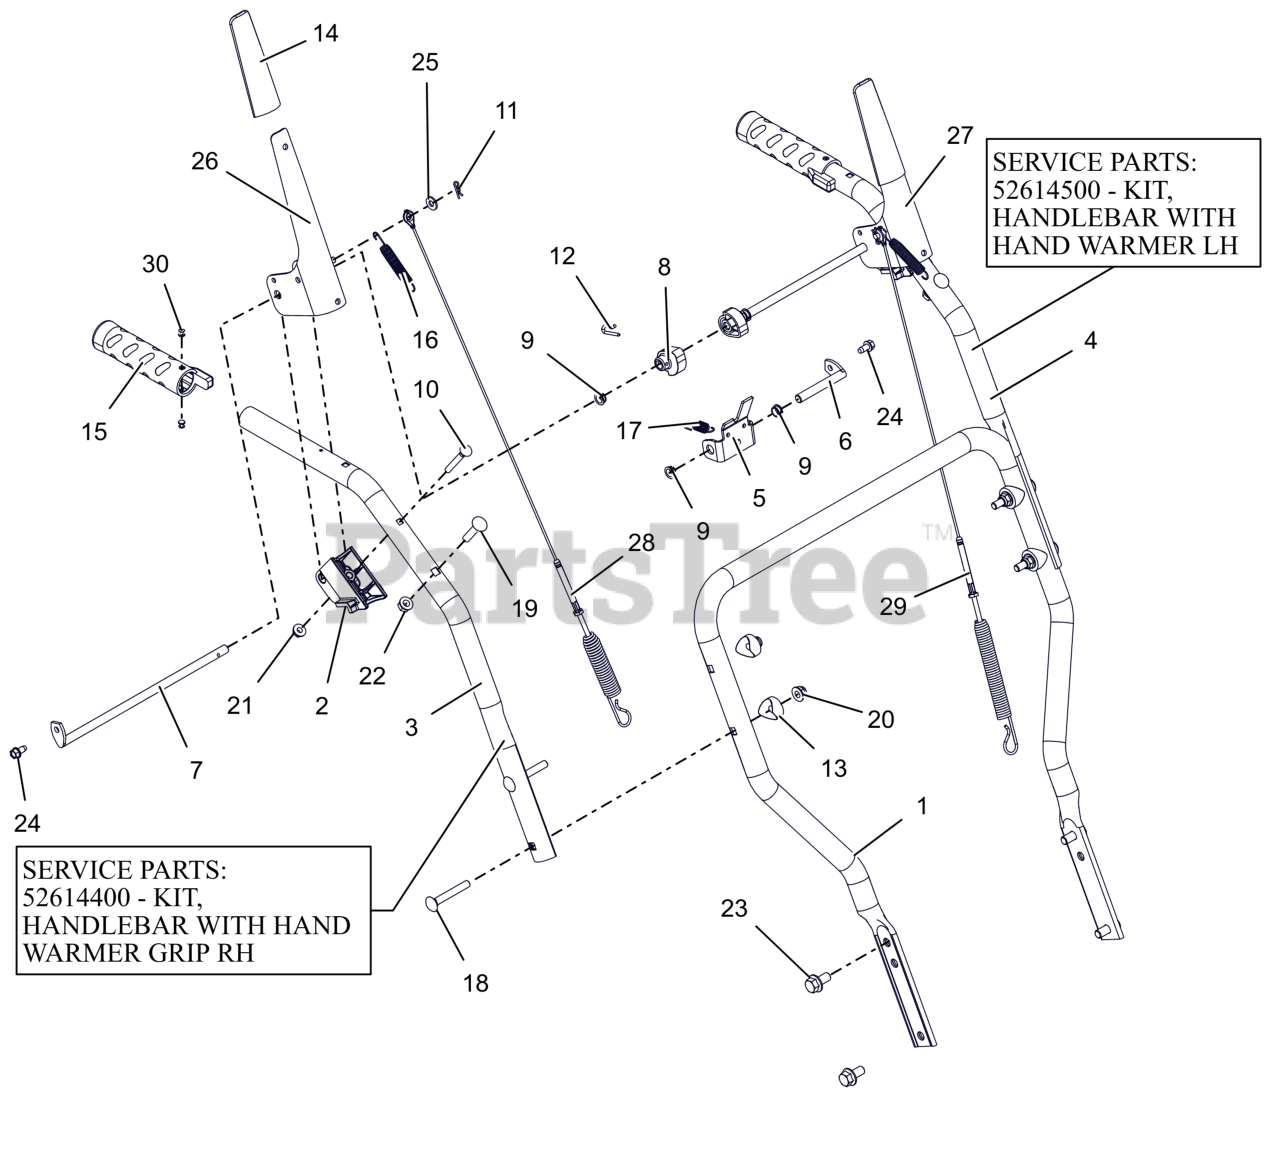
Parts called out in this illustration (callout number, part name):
1	HANDLEBAR, LOWER
2	BLOCK, CLUTCH PADDLE
3	HANDLEBAR, UPPER - RH
4	HANDLEBAR, UPPER - LH
5	BRACKET, INTERLOCK ARM
6	ROD, PIVOT - INTERLOCK
7	ROD, PADDLE MOUNT - PRO
8	CAM, INTERLOCK
9	BUSHING, POLYLINER-.38 SNAPIN
10	BLT-RDHDXLSQNK .25-20X2.0 G5YZ
11	PIN, HAIR #178 .06X.77 ZCC
12	PIN, SPRING CLIP
13	SPACER, HANDLEBAR
14	SLEEVE, CLUTCH PADDLE-GRAY
15	GRIP,HEATED HANDLE-GRAY
16	SPRING, EXTENSION
17	SPRING-EXT .047X.438X1.45
18	BLT, RHSN .31-18X2.25 G5 ZCC
19	BLT,RHSN .31-18X1.50 G5 ZCC
20	NUT,LK-NYL-FLG .31-18 G5ZC120
21	NUT-LK-CTR-FLG .25-20 ZC120
22	NUT-LK-TOP-FLG .312-18 GF ZCC
24	SCR-TAP .25-20X.50 HWH ZCC
25	WSHR,FLT .281X.625X.065 ZCC
26	LEVER, CLUTCH-RH
27	LEVER, CLUTCH-LH
28	CABLE, AUGER (DELUXE & PRO)
29	CABLE, UPPER TRACTION
30	RVT-POP #43 .125X.313 STL ZINC
